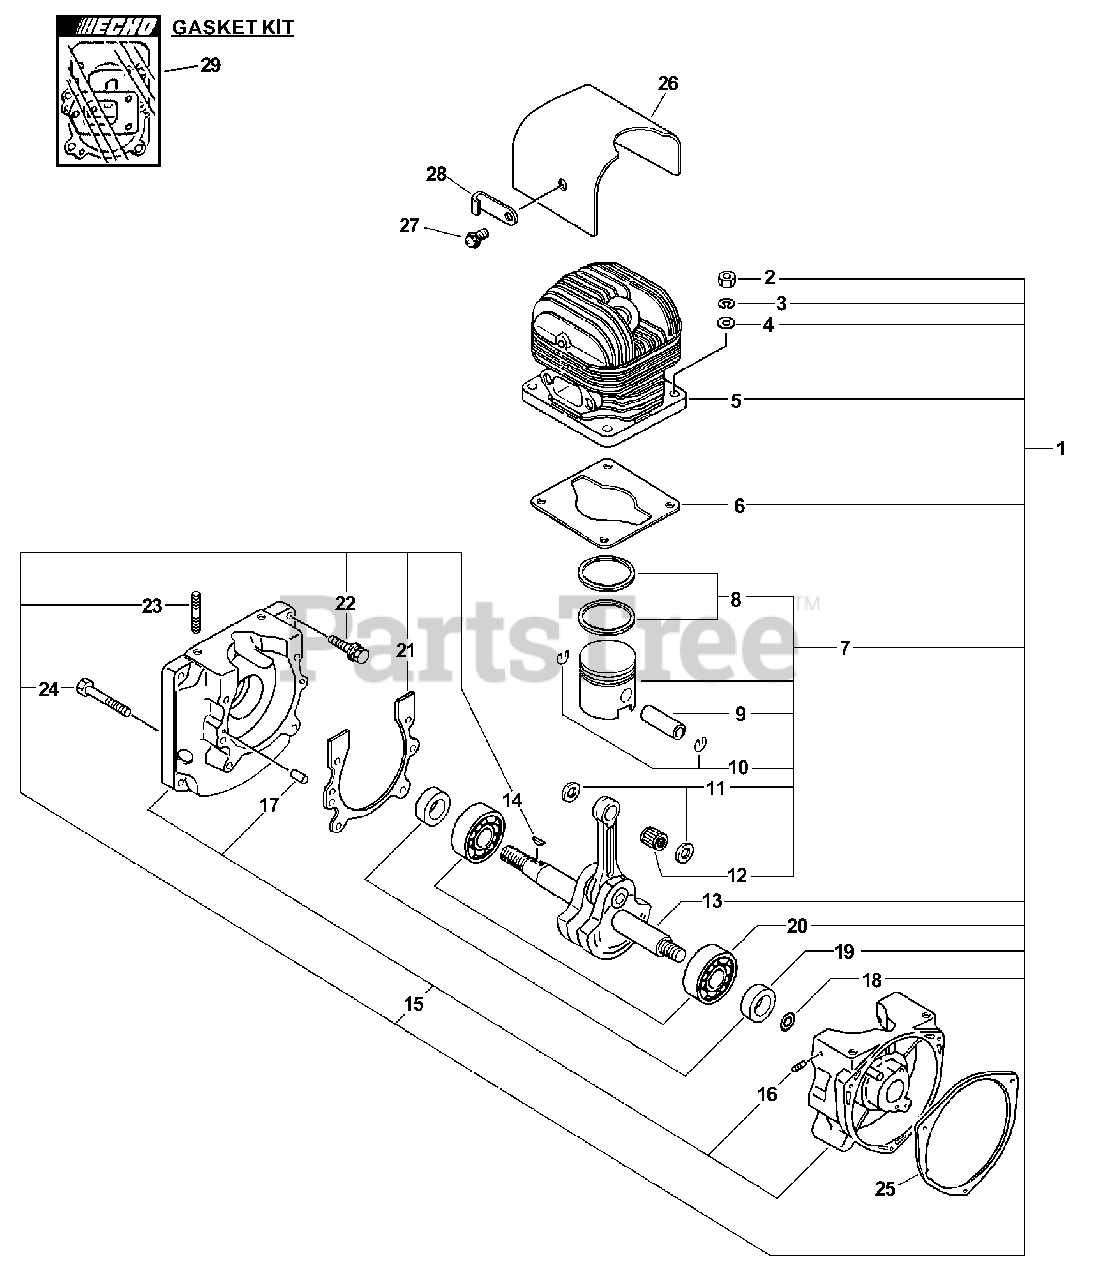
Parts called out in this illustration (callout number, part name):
1	SHORT BLOCK -- SB1056
2	LOCKNUT - 6
3	LOCKWASHER - 6
4	WASHER - 6
5	CYLINDER
6	GASKET, CYLINDER
7	PISTON KIT
8	RING, PISTON
9	PIN, PISTON
10	RING, RETAINING - 8
11	SPACER, PISTON
12	BEARING, NEEDLE
13	CRANKSHAFT ASSY
15	CRANKCASE KIT
16	CONNECTOR
17	PIN - LOCATING
18	WASHER - 10
19	SEAL, OIL
20	BEARING, BALL - 6202
21	GASKET, CRANKCASE
22	BOLT - 6X25
25	GASKET, STARTER
26	SHIELD, CYLINDER
27	BOLT - 6X10
29	GASKET KIT
